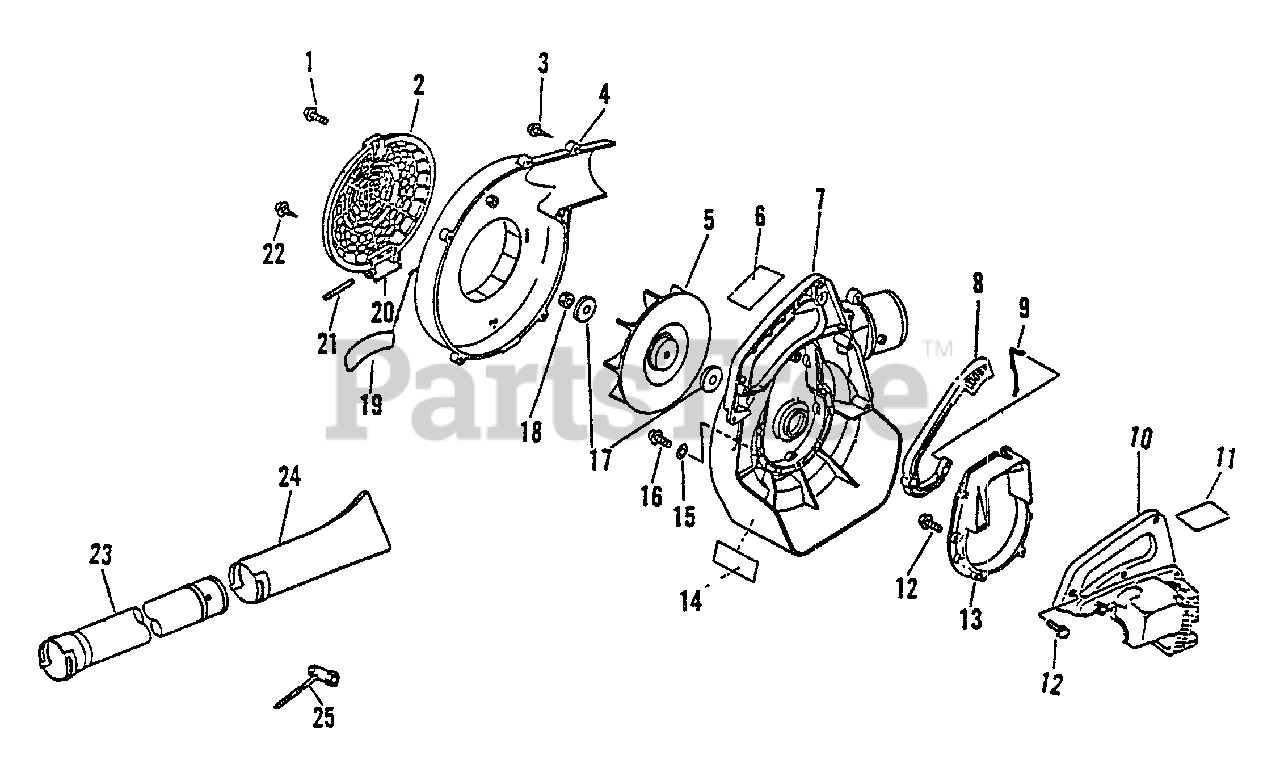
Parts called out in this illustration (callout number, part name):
1	SCREW - 5X18
2	GUARD, DEBRIS
3	SCREW - 5X20 -- TAPPING
4	COVER, FAN - RIGHT
5	FAN
6	LABEL - NOISE
7	COVER, FAN - RIGHT
8	TRIGGER, THROTTLE
9	ROD, THROTTLE
10	COVER, ENGINE
11	LABEL - HOT SURFACE
12	SCREW - 4X18
13	BRACKET, ENGINE
14	LABEL - CAUTION
16	SCREW - 4X22
17	WASHER - 8
19	LABEL - MODEL LBH-2100
22	SCREW - 5X14
23	TUBE, BLOWER - STRAIGHT
24	NOZZLE - FAN HEAD
25	T-WRENCH - 13X19mm
